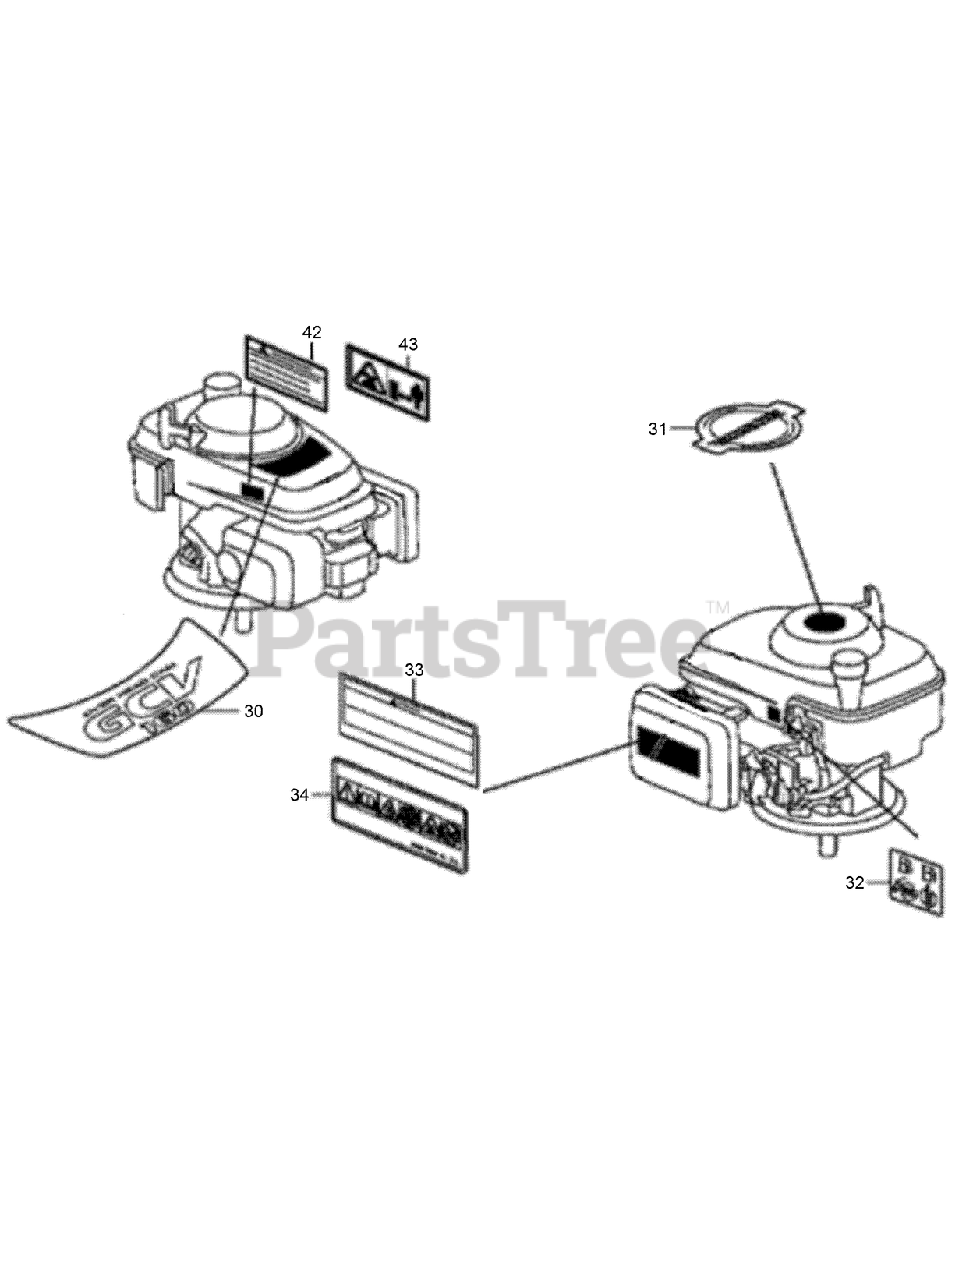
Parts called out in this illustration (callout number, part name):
30	MARK-EMBLEM
31	MARK-RECOIL COVER
32	MARK-FUEL COCK CAUTION
33	MARK-OPERATOR CAUTION (ENGLISH)
34	MARK-OPERATOR CAUTION
42	MARK-EXHAUST CAUTION (ENGLISH)
43	MARK-EXHAUST CAUTION
